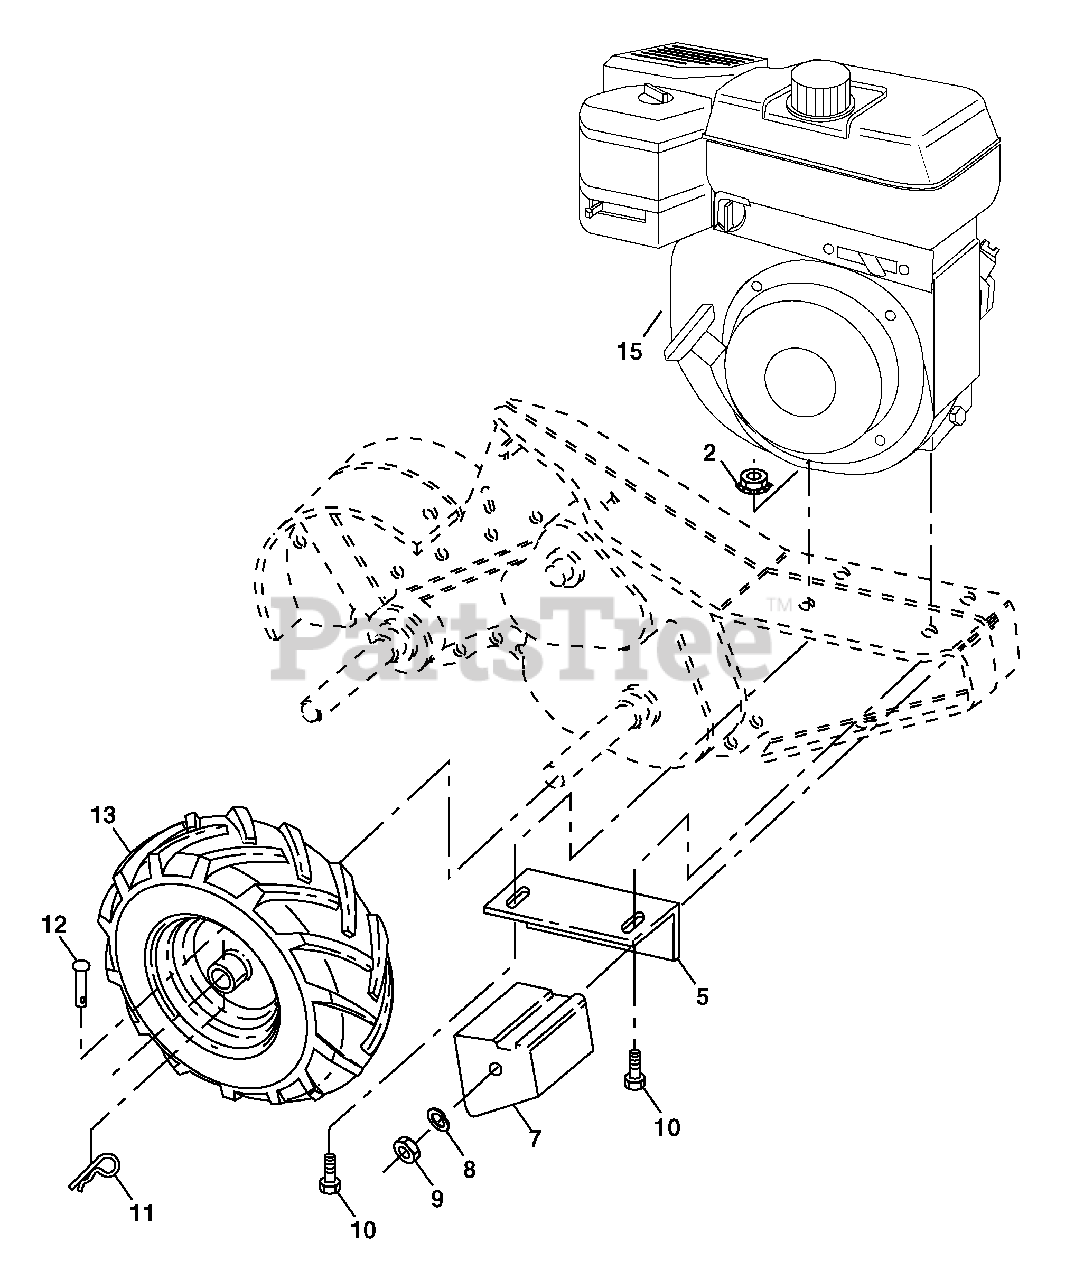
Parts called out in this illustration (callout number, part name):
2	Locknut, Hex, Flange 5/16-18
5	Bracket, Reinforcement
7	Counter Weight, R.H.
8	Washer, Lock 3/8
9	Nut, Hex 3/8-16
10	Bolt, Hex 5/16-18 x 1-1/2
11	Clip, Hairpin
12	Rivet, Drilled
13	Rim
13	Tire Valve
